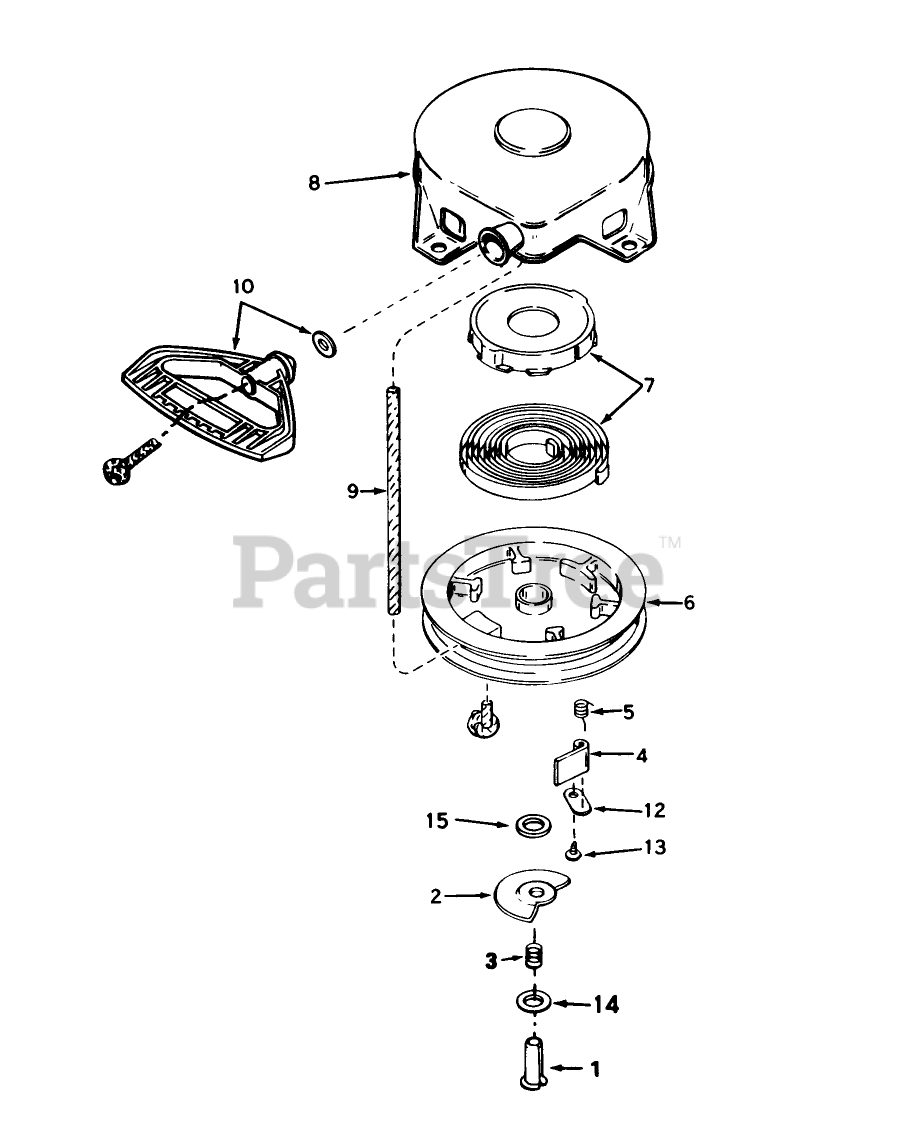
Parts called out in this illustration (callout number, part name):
1	Pin Spring
2	Washer
3	Brake Spring
4	Dog-Starter
5	Spring-Dog
6	Pulley
7	Spring Keeper Assy
8	Housing-Starter
9	Rope-Starter
10	Handle-Starter, Mitten Grip
12	Retainer-Dog
13	Screw
14	Washer
15	Washer
